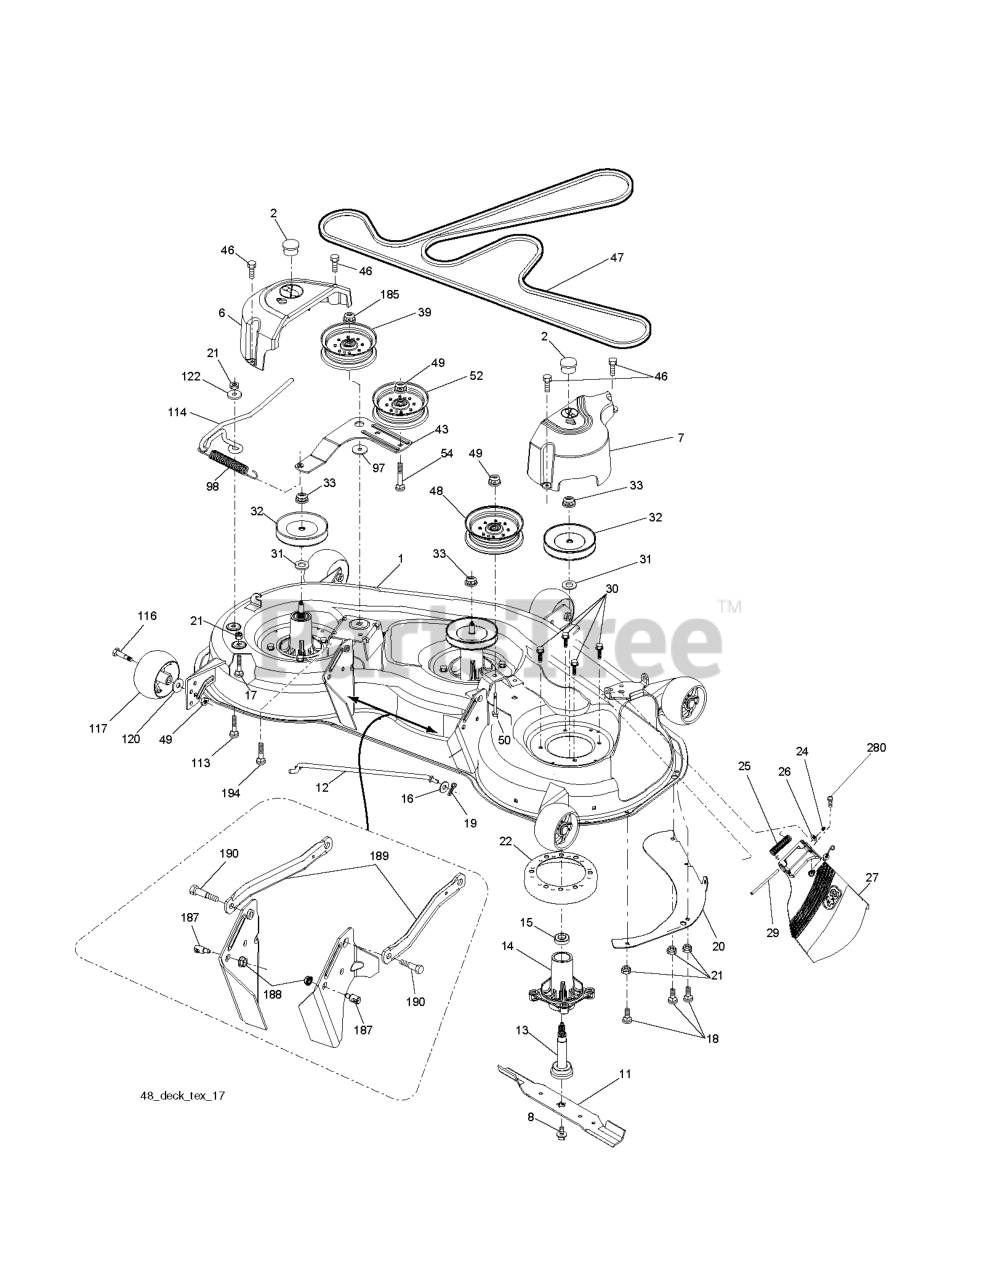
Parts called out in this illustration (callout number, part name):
1	DECK WELDMENT
8	BOLT 7/16 ASM BLADE
11	48" HI-LIFT BLADE
12	ROD.ANTI.SWAY.48/54"TE
13	SHAFT ASM MANDREL
14	RP.HOUSING.MANDREL.4PT.
16	WASHER
17	BOLT.CARR.5/16-18X5/8.SHORT
18	BOLT
19	PIN.COTTER.5/16.BOW TI
20	BAFFLE, VORTEX MWR
21	LOCKNUT
22	STRIPPER.MANDREL.ROUND.BLACK
24	CAP-SLEEVE LT
25	SPRING, TORSION
26	NUT PUSH M
29	ROD.HINGE
30	SCREW, WASHER HEAD
31	WASHER.SPACER.MANDREL
32	PULLEY MANDREL
33	NUT.FLANGE.LOCK.TOP
39	RB PULLEY.IDLER.4.50/HUB SPEC
46	SCREW.1/4-20X5/8
47	BELT.DRIVE.DECK
48	PULLEY.IDLER.48"PRIMARY
49	NUT LOCK FLG 3/8-16 UNC
50	SCREW TT 3/8-16X2-1/4 UNC
52	PULLEY.IDLER.2006
54	BOLT.3/8-16X1.50
98	SPRING, DECK DRIVE
114	ROD.TENSION.RELIEF.TEX (2 2)
116	BOLT.SHOULDER.3/8-16X3-5/8.
117	RP WHEEL. GUAGE RALLY
120	WASHER
122	BUSHING.RELIEF.TENSION
185	NUT.LOCK.FLANGE.7/16
187	STUD.FASTNER.W/ANTI-ROTATE
188	NUT LOCK HEX FLANGE 5/16-18
189	ARM.SUSPENSION.MOWER
190	BOLT.SHOULDER
194	BOLT.CARR.SQNK.7/16
